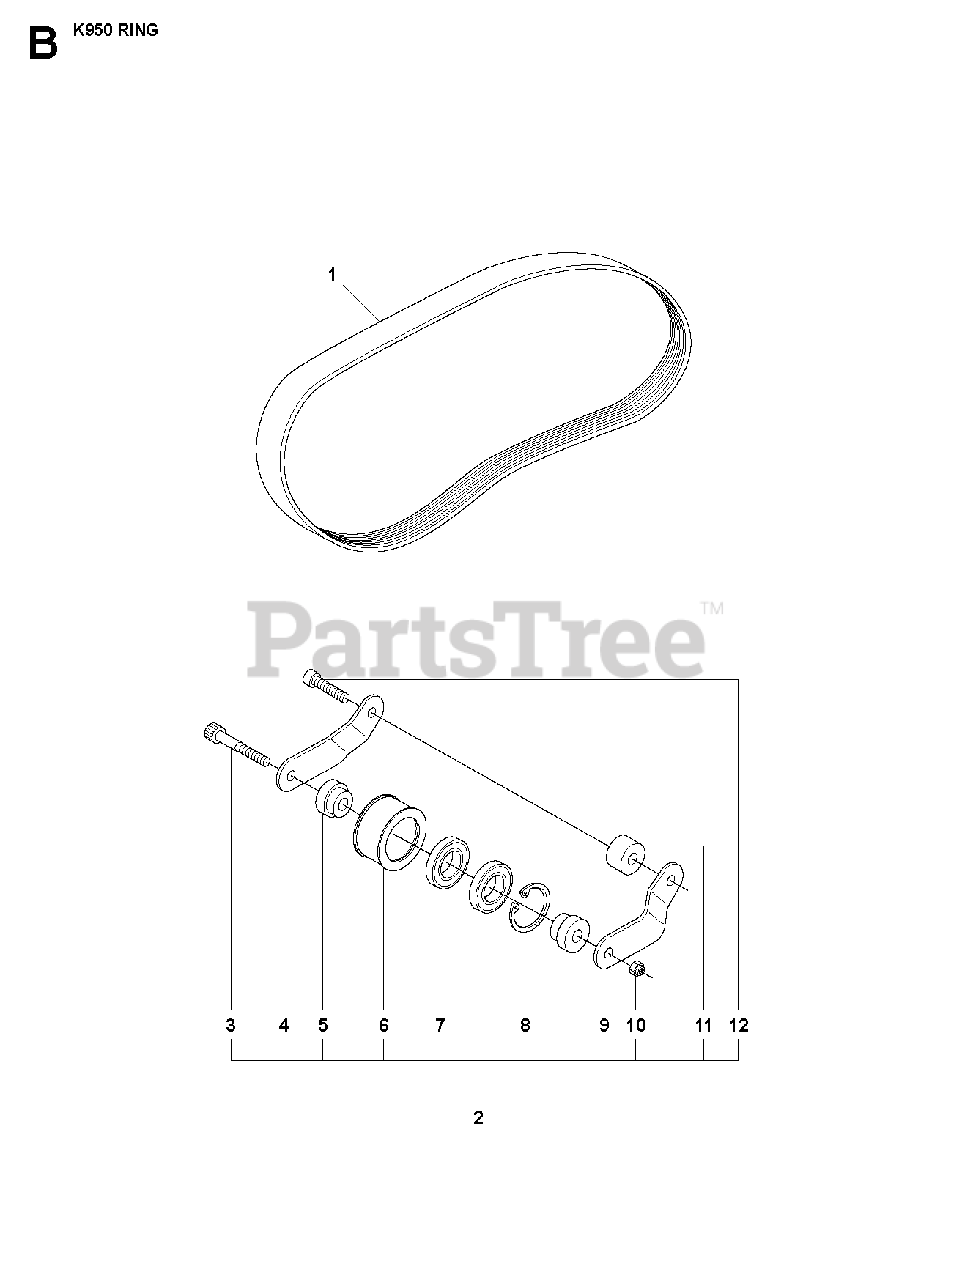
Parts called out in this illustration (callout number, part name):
2	BELT TENSIONER ASSYIncl. 3, 4, 5, 6, 7, 8, 9, 10, 11, 12
7	BALL BEARING
10	NUT
